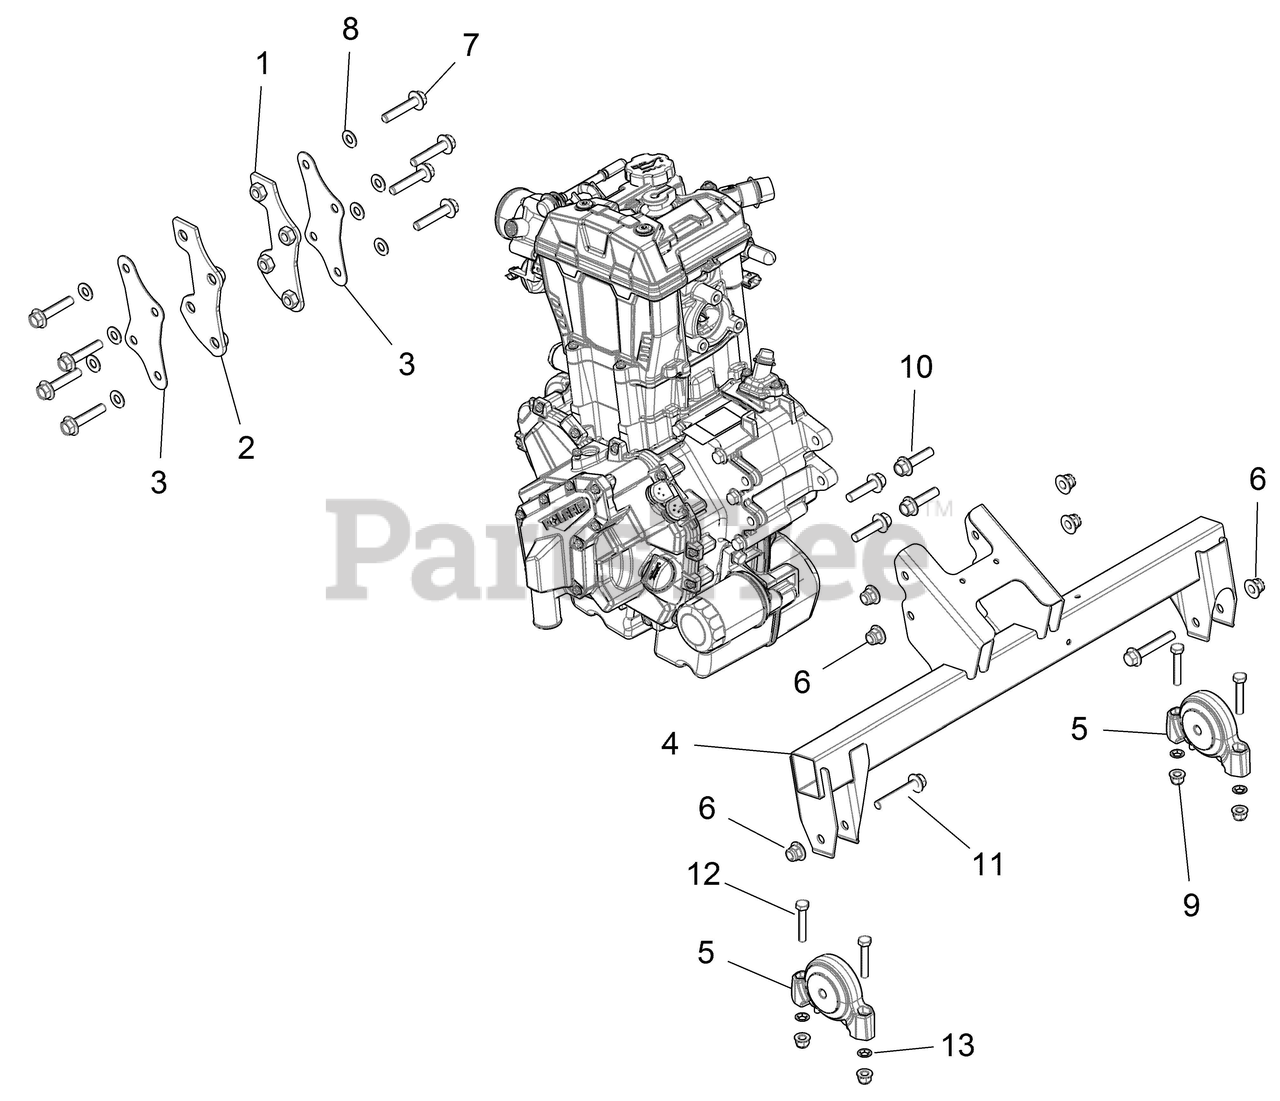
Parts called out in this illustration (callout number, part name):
1	WELD-TRANS,INNER,LEFT
2	WELD-TRANS,INNER,RIGHT
3	BRKT-COUPLER,TRANS,OUTER
4	WELD-MOUNT,ENGINE,BLK
5	MOUNT-ISOLATOR,DRIVELINE
6	NUT-M10X1.25,FLG,NYLOC-OLIVE D
7	SCR-M10X1.5X50 8.8 HX/FL ZOD
8	WASHER,3/8 FW
9	NUT-M8X1.25,FLG,NYLOC-OLIVE D
10	SCR-HXFL-M10X1.25X40 8.8 ZOD
11	BOLT-M10X1.25X60,HXFLG-OLIVE D
12	SCR-HH M8X1.25X45 8.8 ZOD
